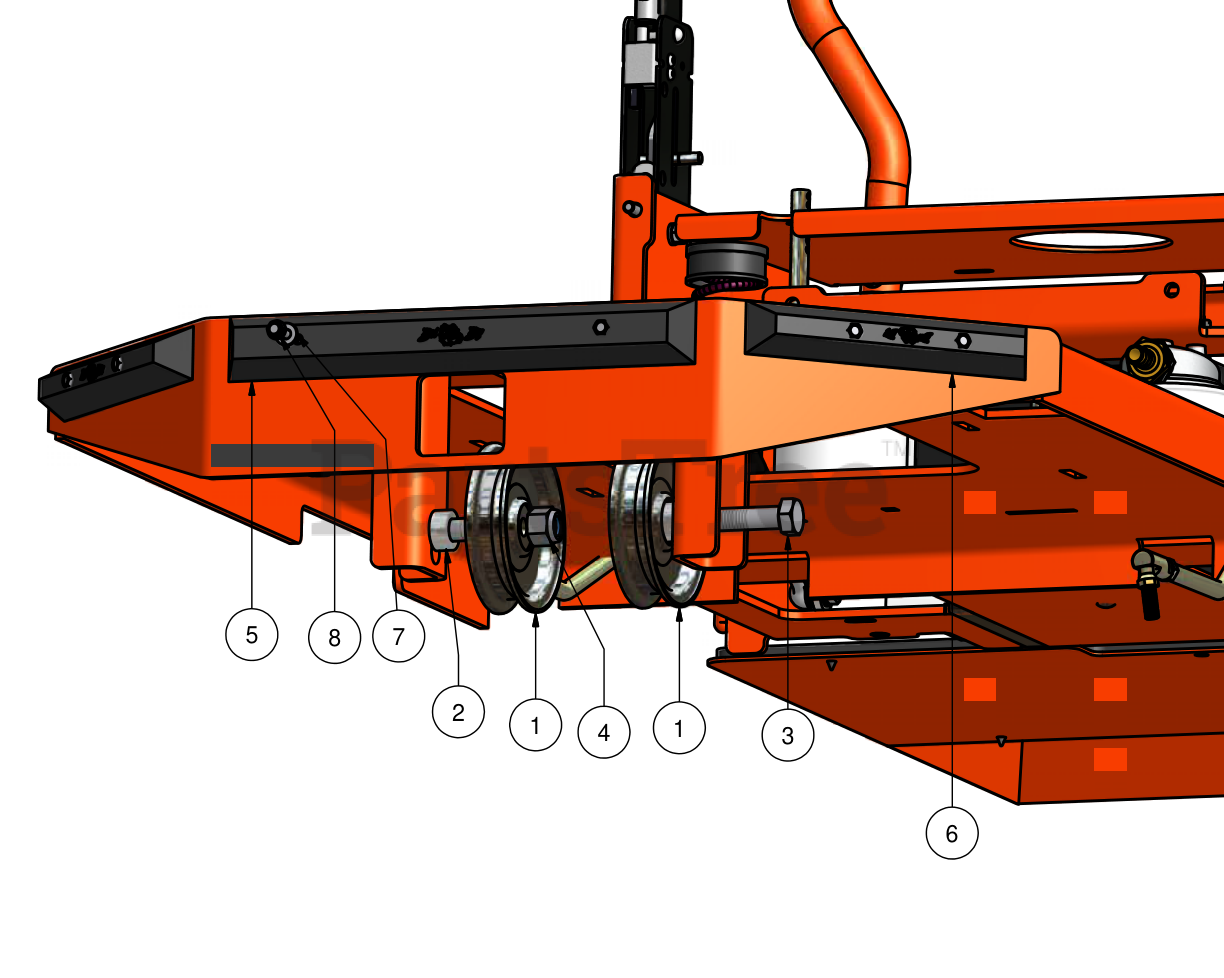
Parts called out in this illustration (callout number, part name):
1	5" V Idler Pulley
2	5/8" x 1/2" Collar Spacer
3	5/8" x 2 1/2" Bolt
4	5/8" Nylock Nut
5	14" Bumper
7	1/4" Flat Washer
8	1/4" x 1 1/2" Self Tapping Screw
